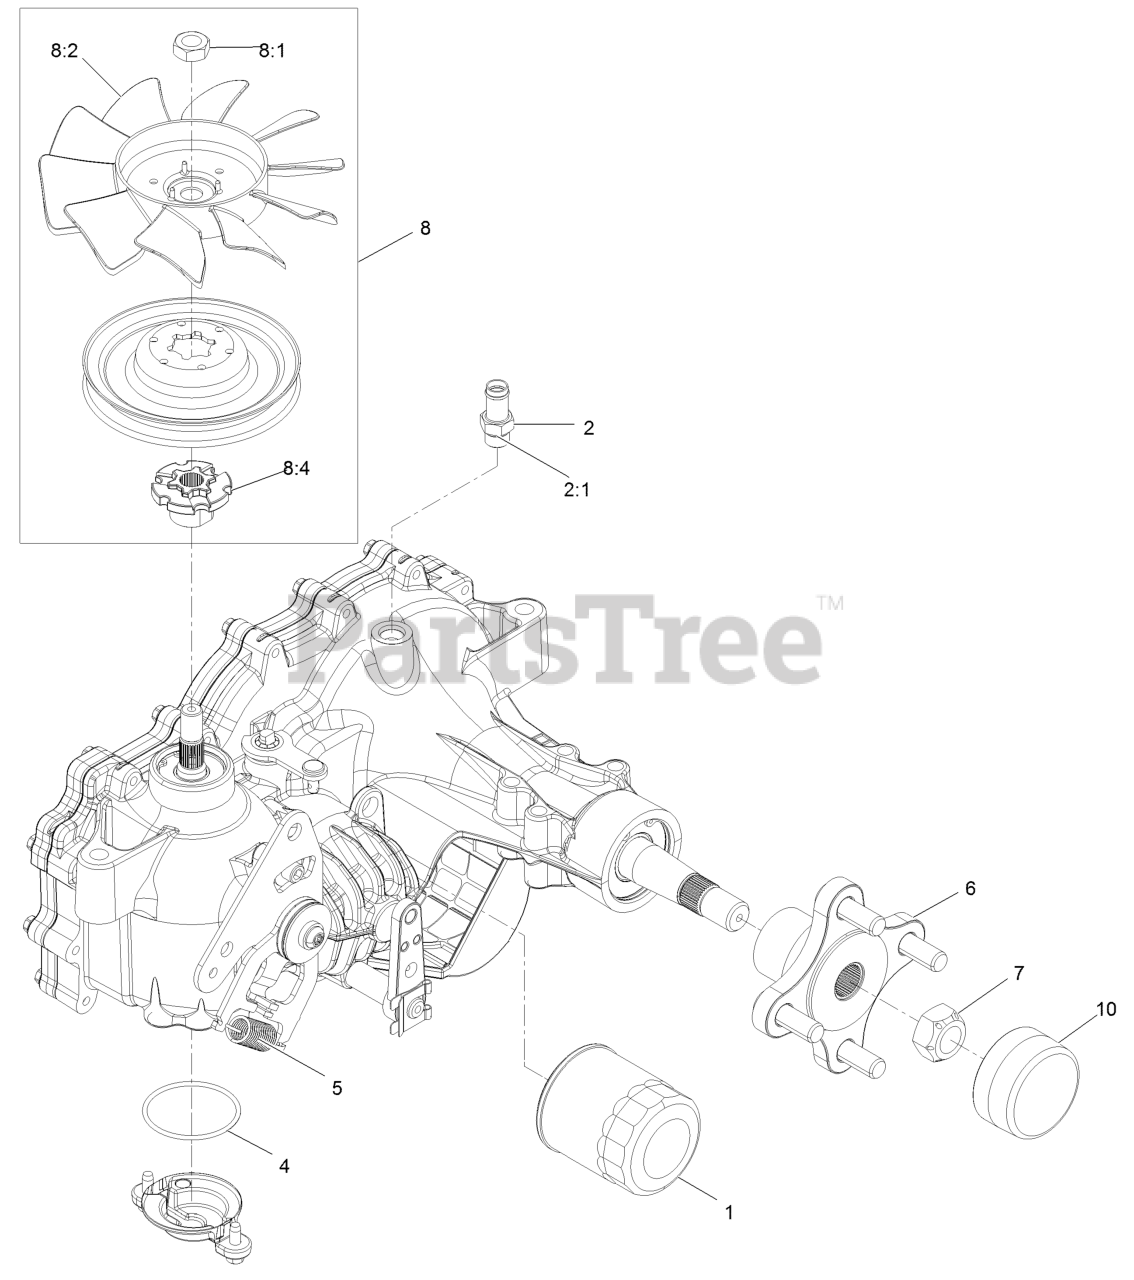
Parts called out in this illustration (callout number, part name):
1	ELEMENT-OIL FILTER, HYD
2	ADAPTER-STRAIGHT
2:1	O-RING
4	O RING-SEAL
5	SPRING-EXTENSION
6	HUB KIT
7	NUT-HUB
8	FAN AND PULLEY KIT
8:4	HUB-PULLEY
10	COVER-NUT, AXLE
